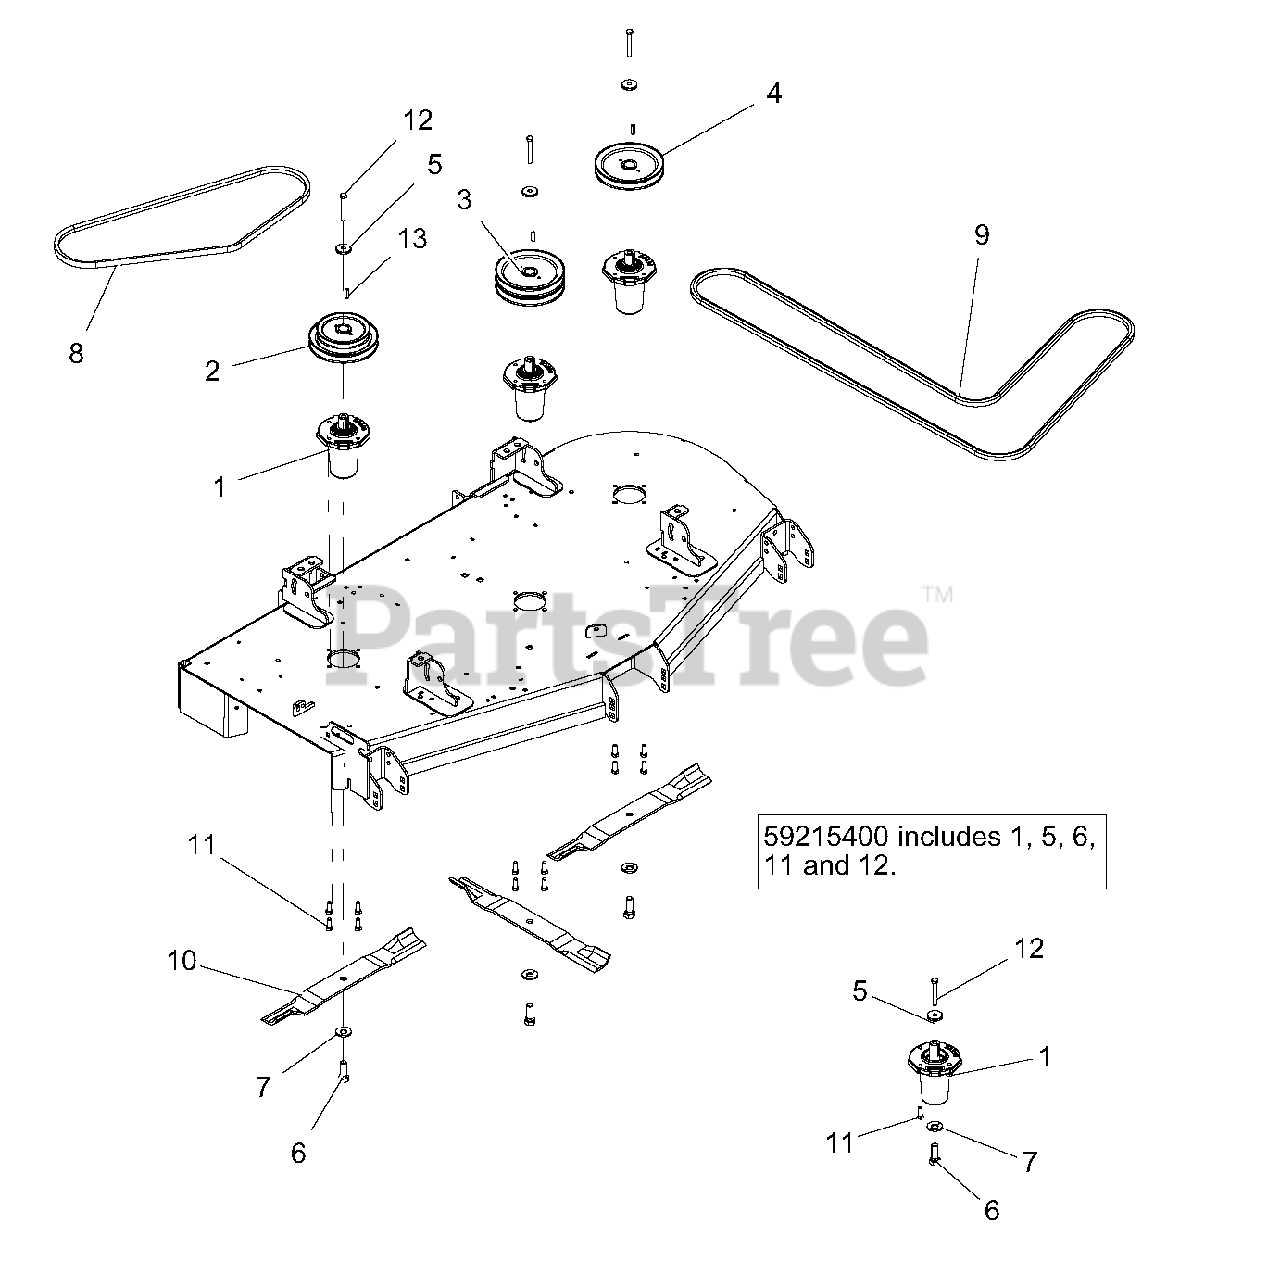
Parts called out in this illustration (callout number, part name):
1	ASM, Maintenance Free Spindle
2	PULLEY, DOUBLE -1" ID X 6.75" & 5.25" OD
3	PULLEY, DOUBLE 1"ID X 6.75"OD-BLACK
4	PULLEY, V-1" ID X 6.75" OD-BLACK
5	RETAINER, SHEAVE SPINDLE
6	BLT, HEX .62-18X1.75 GR8 YWZC
7	WSHR, BLVL .63X1.625X.14
8	BELT, B 63.00 RAW COGGED
9	BELT, BB 133.00 WRAPPED HEX
10	BLADE, MOWER 60"
11	BLT-HEX .38-16X1.00 GR5 YWZC EP30
12	BLT-HEX .38-16X2.75 GR8 YWZC
13	KEY-SQ .250X.250X1.00 RC 40-50
